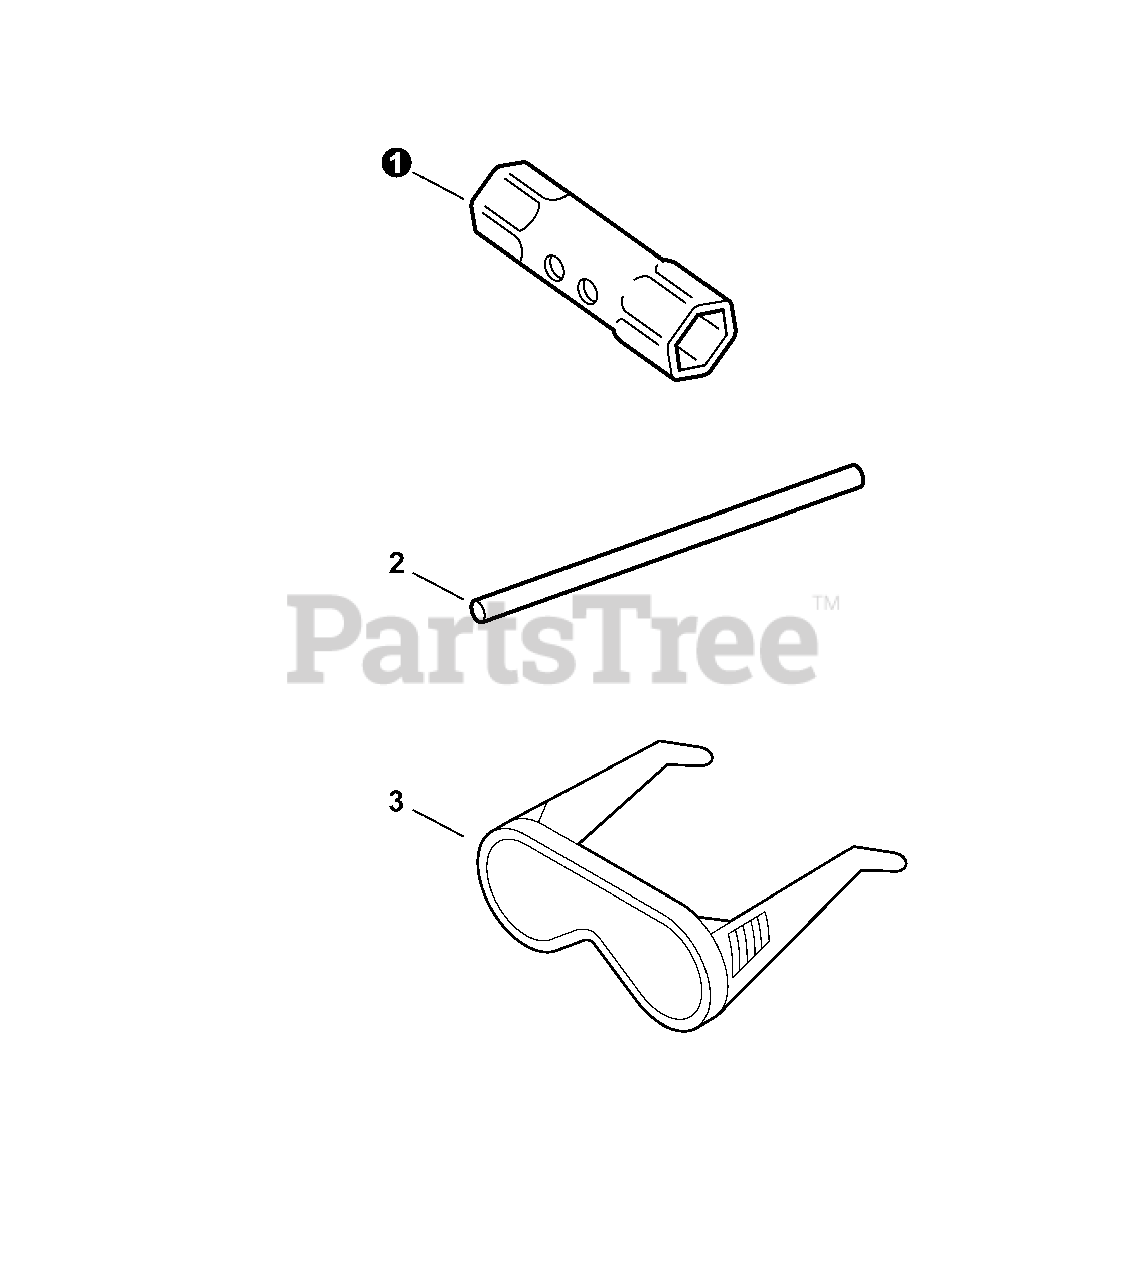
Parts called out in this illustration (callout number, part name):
1	SOCKET WRENCH 17×14.5 MM
2	TOOL, LOCKING 5×120 MM
3	GLASSES, SAFETY
